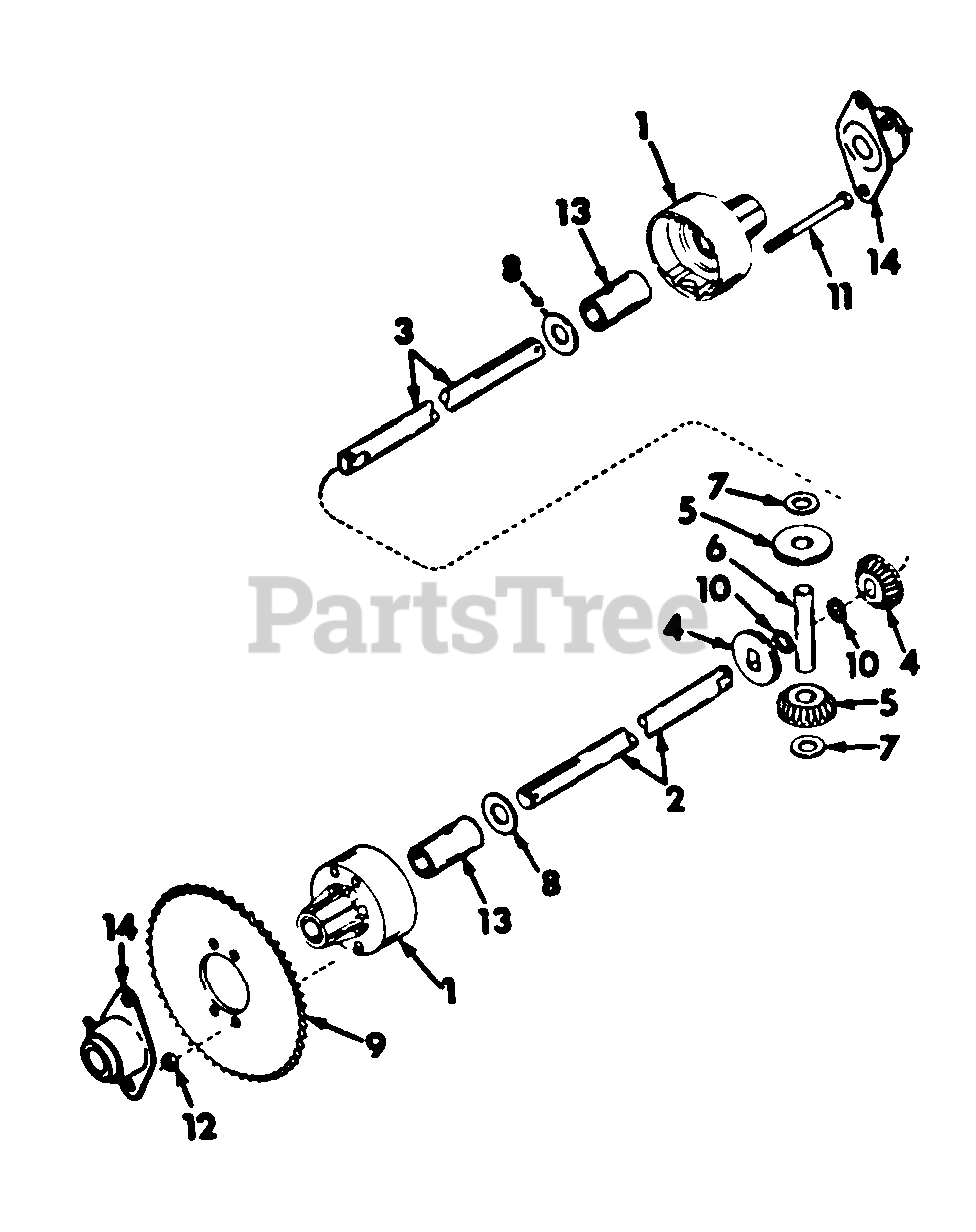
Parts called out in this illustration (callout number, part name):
1	HOUSING, DIFFERENTIAL CARRIER -SPROCKET SIDE-
1	HOUSING, DIFFERENTIAL CARRIER
4	GEAR, BEVEL -16 T
5	GEAR, PINION -16 T
7	WASHER, THRUST BRG RACE
9	SPROCKET, 45 T
10	RING, .689 HVY EXT RET
11	BOLT, 5/16-18 SPECIAL
12	NUT, 5/16-18 LOCK
14	BEARING, REAR AXLE FLANGE BALL
